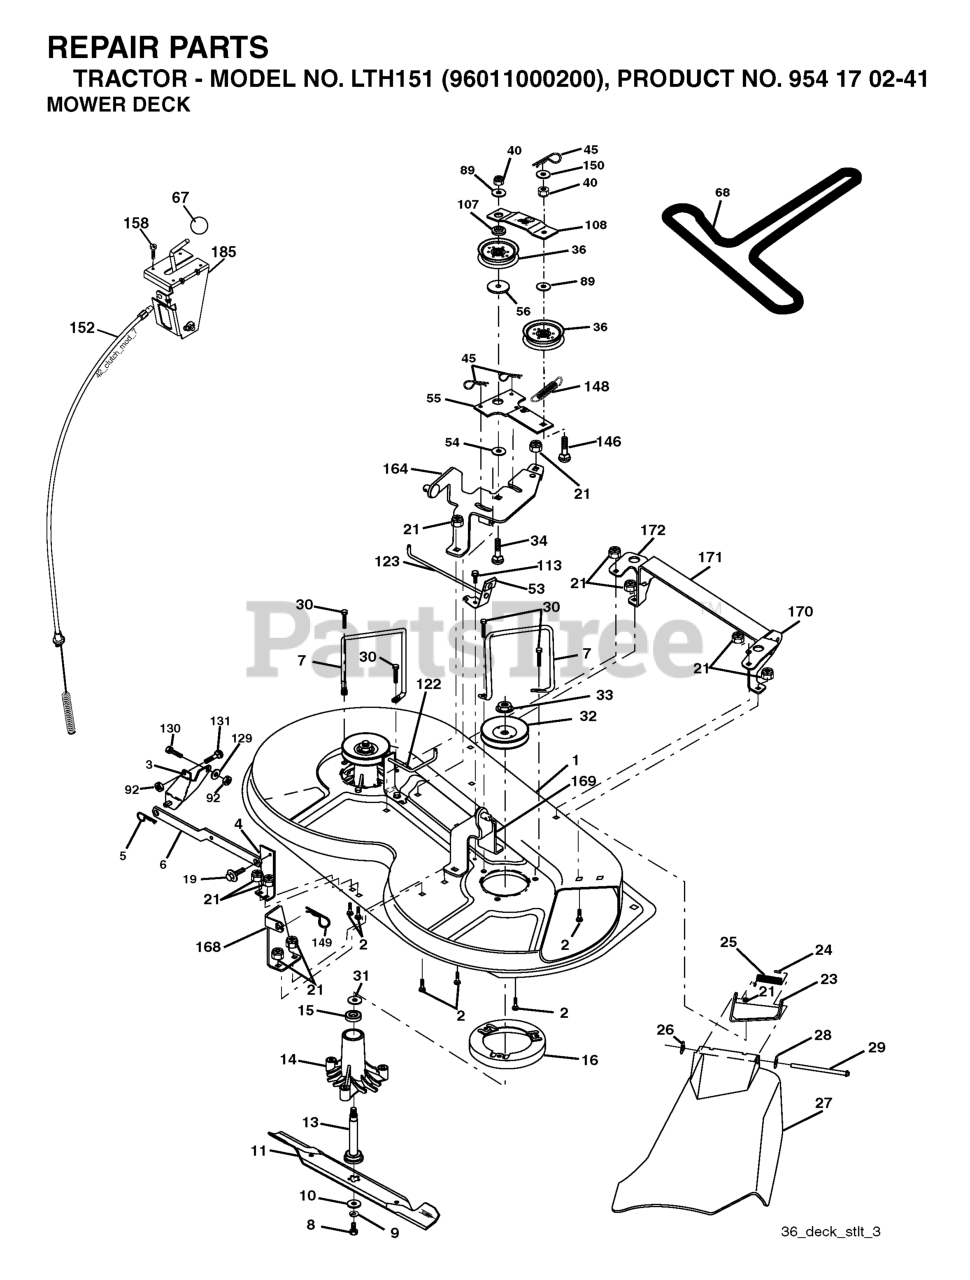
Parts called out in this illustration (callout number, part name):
2	RP BOLT 5/16-18 X3/4 ZN/YEL GR
3	BRKT ASM SWAY BAR
5	RETAINER-SPRNG RB
6	BAR SWAY DECK
8	BLADE BOLT
9	LOCKWASHER
10	WASHER.BLADE
11	BLADE, HI-LIFT 36" PREMIUM
13	SHAFT ASM VENT
14	HOUSING.MANDREL.VENTED (MACHD)
16	STRIPPER.MANDREL.ROUND.BLACK
19	BOLT SHD 5/16-18
21	LOCKNUT
23	BRACKET ASM DEFLECTOR
24	CAP-SLEEVE LT
25	SPRING TORSION
26	NUT PUSH M
27	CONSOLE.STLT.5SP.BLK
28	Washer 11/32 x 5/8 x 16 Ga SD
29	HINGE ROD
30	SCREW, WASHER HEAD
31	WASHER.SPACER.MANDREL
32	PULLEY, MANDREL
33	NUT, FLG TOPLOCK 9/16"
36	FLAT IDLER PULLEY
45	RETAINER M
53	BRAKE ASSEMBLY
56	SPACER.RETAINER.MOWER
67	KNOB T (3/8 HOLE)
68	V-BELT.MOWER.
89	WASHER
92	NUT
107	SPACER.IDLER.ARM
108	STIFFENER.IDLER.ARM
113	Screw 5/16-18 x 1/2 Hex, Self Tapping 5/16-18 x 1/2
129	WASHER
131	BOLT D
146	BOLT, CARRIAGE IDLER
148	IDLER RETURN SPRING
149	SPRING.RETAINER.YELLOW.ZINC
158	SCREW
171	BRACE.SUPT.SUSP.FRT.CRD
185	HEAD ASM. CABLE CLUTCH
